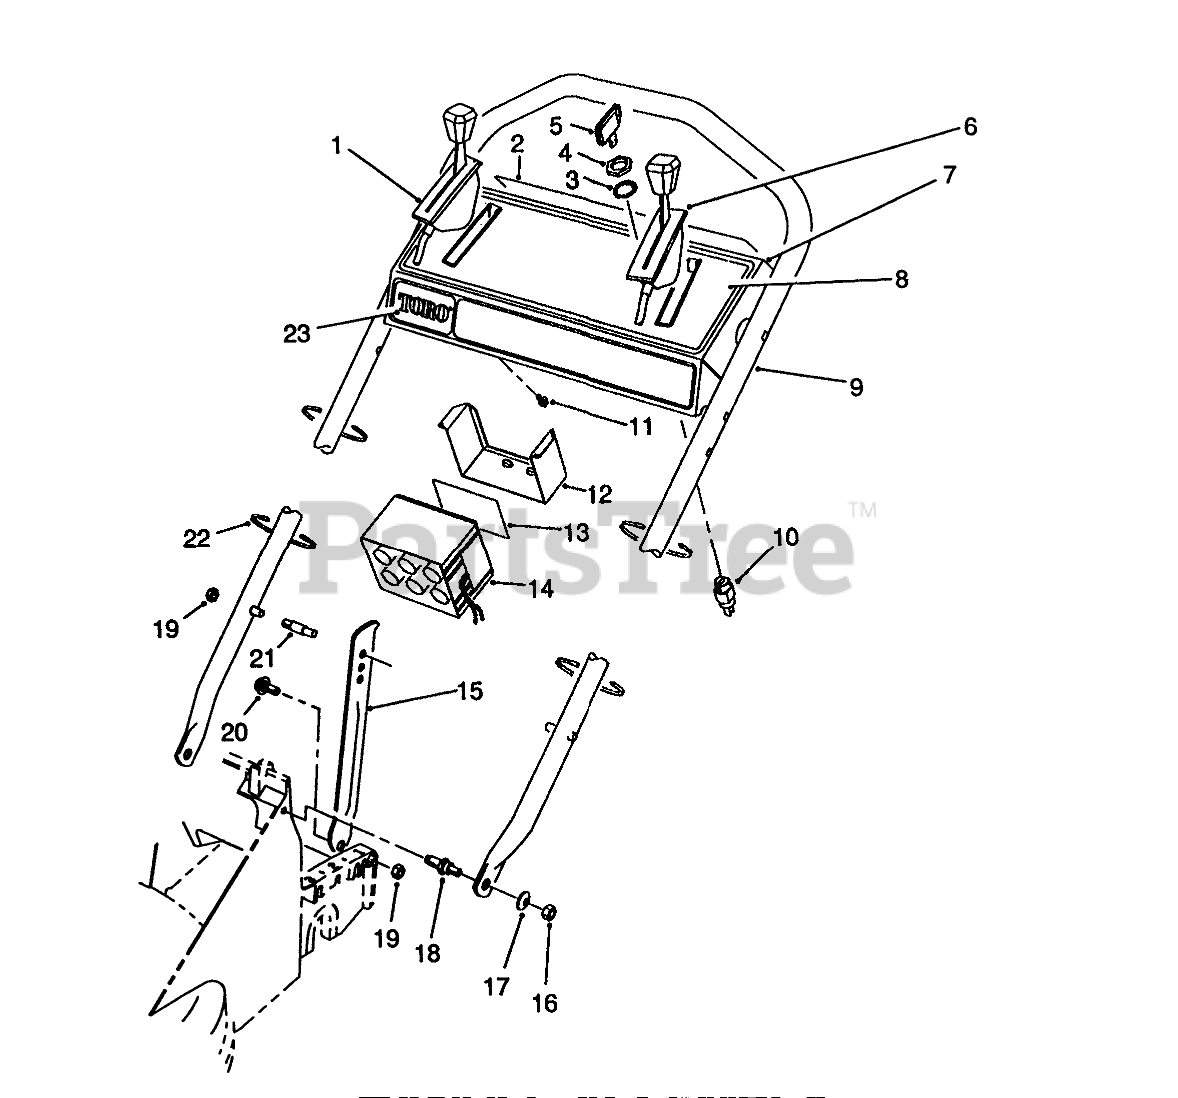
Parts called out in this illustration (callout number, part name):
1	GROUND SPEED CONTROL
2	DECAL-PANEL, DANGER
3	WASHER-TOOTH, INTERNAL
4	NUT-HH
5	KEY-IGNITION
6	ControI-Throttle Bend Type #2 Sheath Lg. 44-3/4" Wire Lg. 2-1/2"
7	Panel-Control (Incl. Ref. #8)
8	DECAL - CONTROL PANEL
9	HANDLE
10	Switch-Starter (Incl. Ref. #3 & 4)
11	SCREW-HWHTF
12	Retainer-Battery
13	Decal
14	Battery (Incl. Ref. #13)
15	HANDLE LATCH
16	NUT-LOCK, NI
17	WASHER-PLAIN
18	SCREW - SHOULDER STUD
19	NUT-LOCK, NI
20	SCREW - SHOULDER
21	HANDLE PIN
22	TIE-CABLE
23	DECAL - KEY LECTRIC
